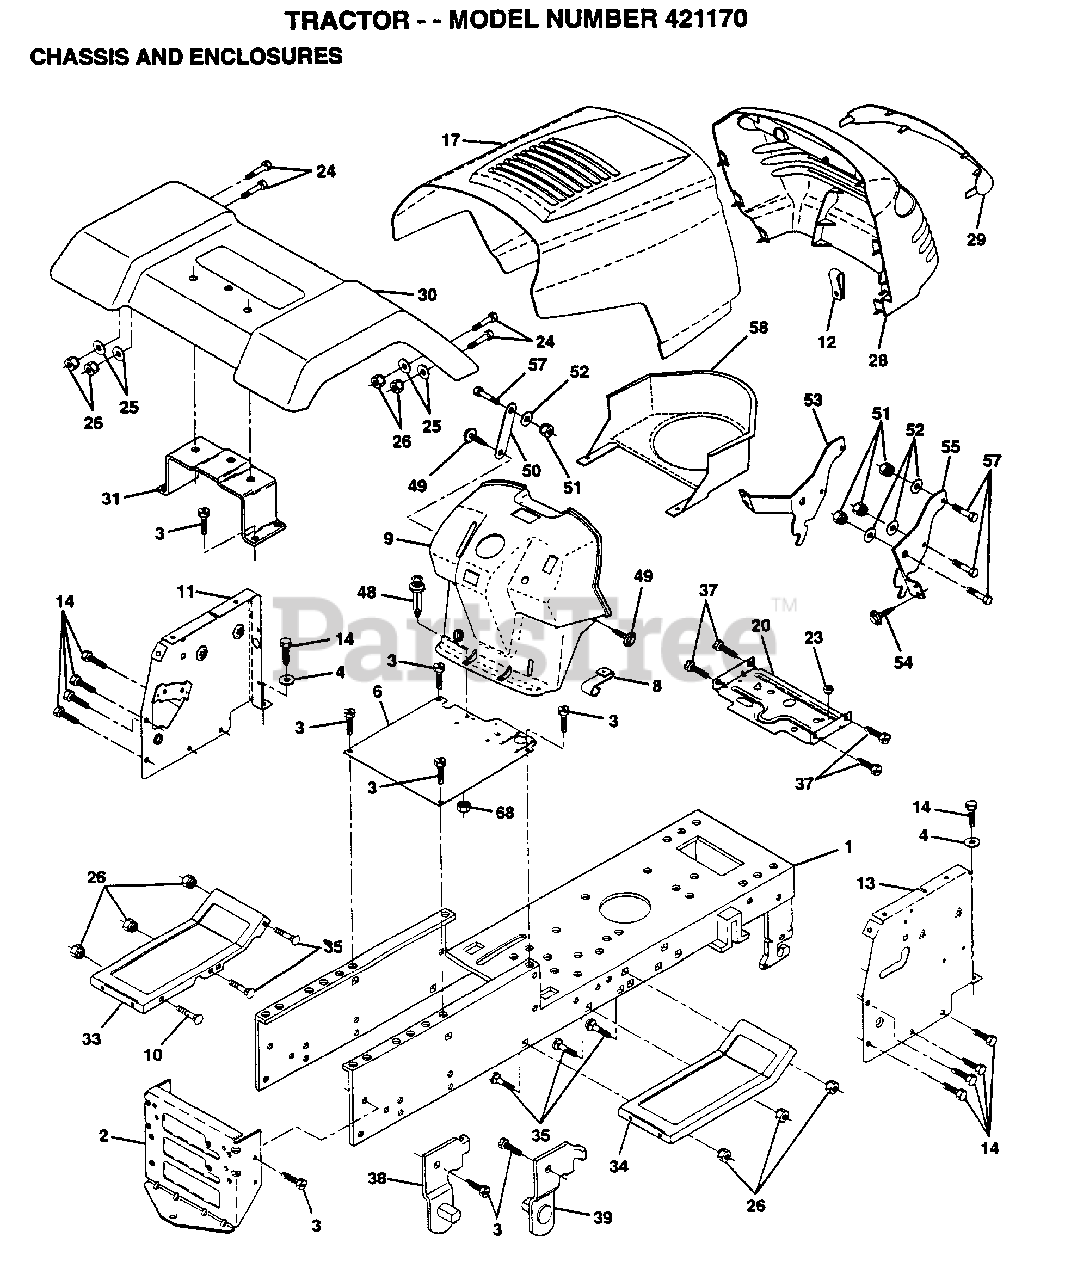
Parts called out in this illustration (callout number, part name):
1	CHASSIS.WLD.11GA
3	SCREW
4	WASHER
8	"CLIP,INSULATOR"
12	CLIP.TINNERMAN
14	SCREW LT
20	PLATE.MTG.BTRY.TK
24	BOLT
25	WASHER
26	NUT
29	LENS GRILLE
31	BRKT FENDER
33	FOOTREST.LH.LT/GT
34	FOOTREST.RH.LT/GT
35	BOLT
37	SCREW
38	BRACKET ASM LH
39	BRACKET ASM RH
48	RIVET.PUSH.PLATE
49	SCREW HEX CRT
50	BRACE SUPT DASH
51	NUT
52	WASHER
53	BRACKET.GRILLE.LH
55	BRACKET.GRILLE.RH
58	DUCT.AIR.B&S.18HP
68	NUT
